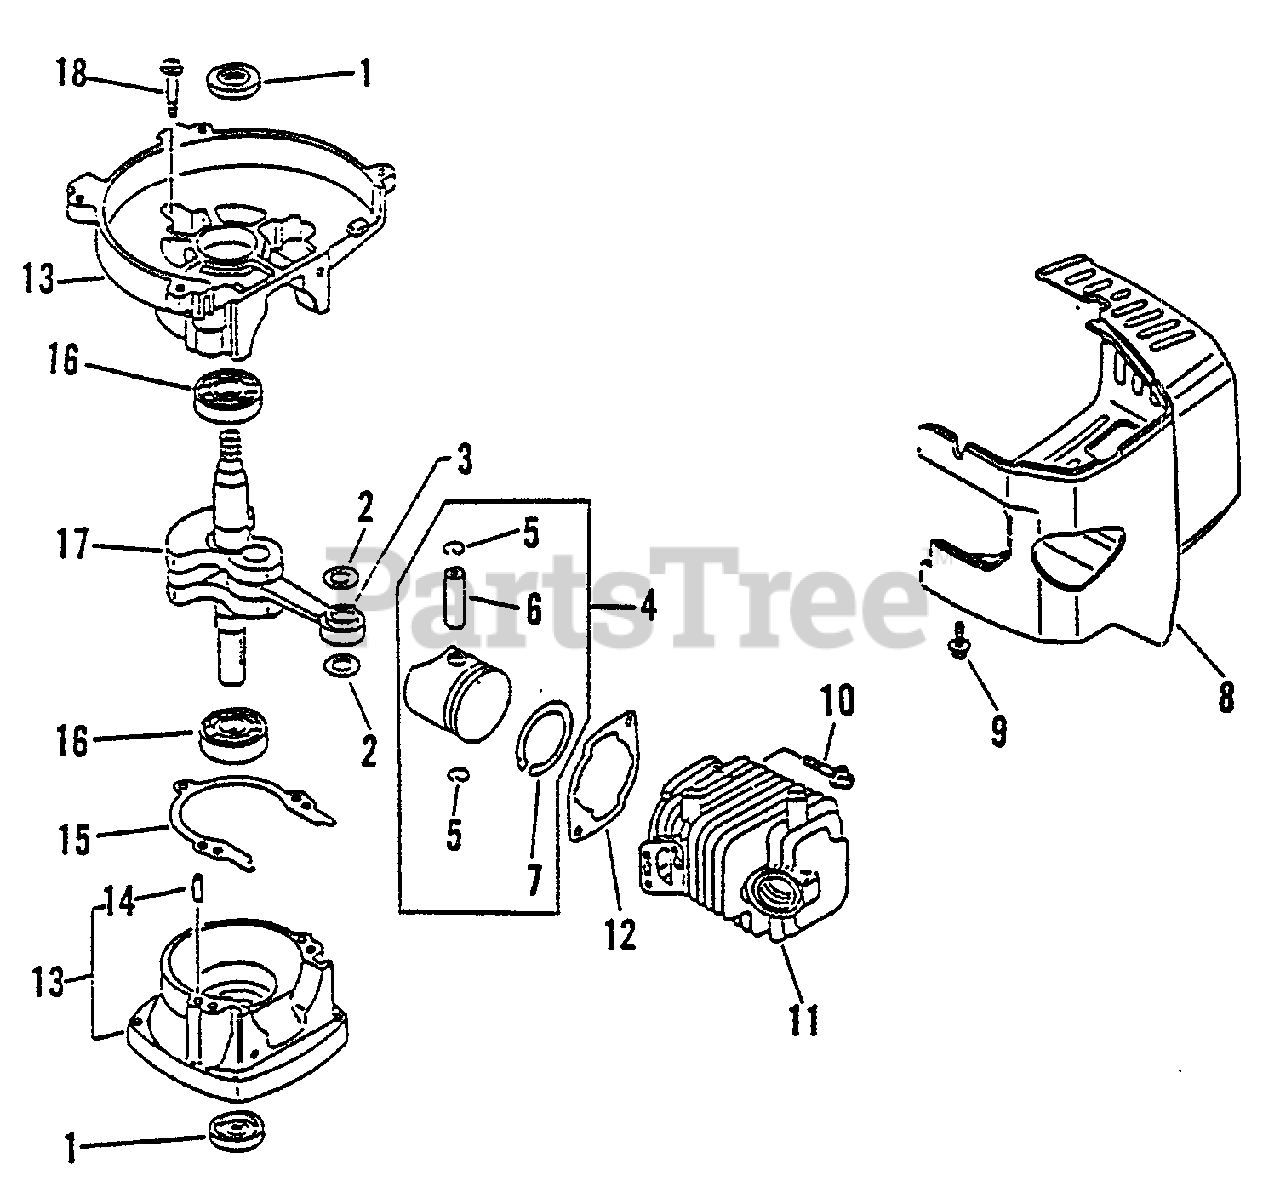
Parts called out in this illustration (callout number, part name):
1	SEAL, OIL
2	SPACER, PISTON
3	BEARING, NEEDLE
4	PISTON KIT
5	RING, RETAINING
6	PIN, PISTON
7	RING, PISTON
8	COVER, ENGINE
9	SCREW - 4X20
10	SCREW - 5X22
11	CYLINDER
12	GASKET, CYLINDER
13	CRANKCASE KIT
14	PIN - LOCATING
15	GASKET, CRANKCASE
16	BEARING, BALL - 6201
17	CRANKSHAFT ASSY
18	SCREW - 5X28
